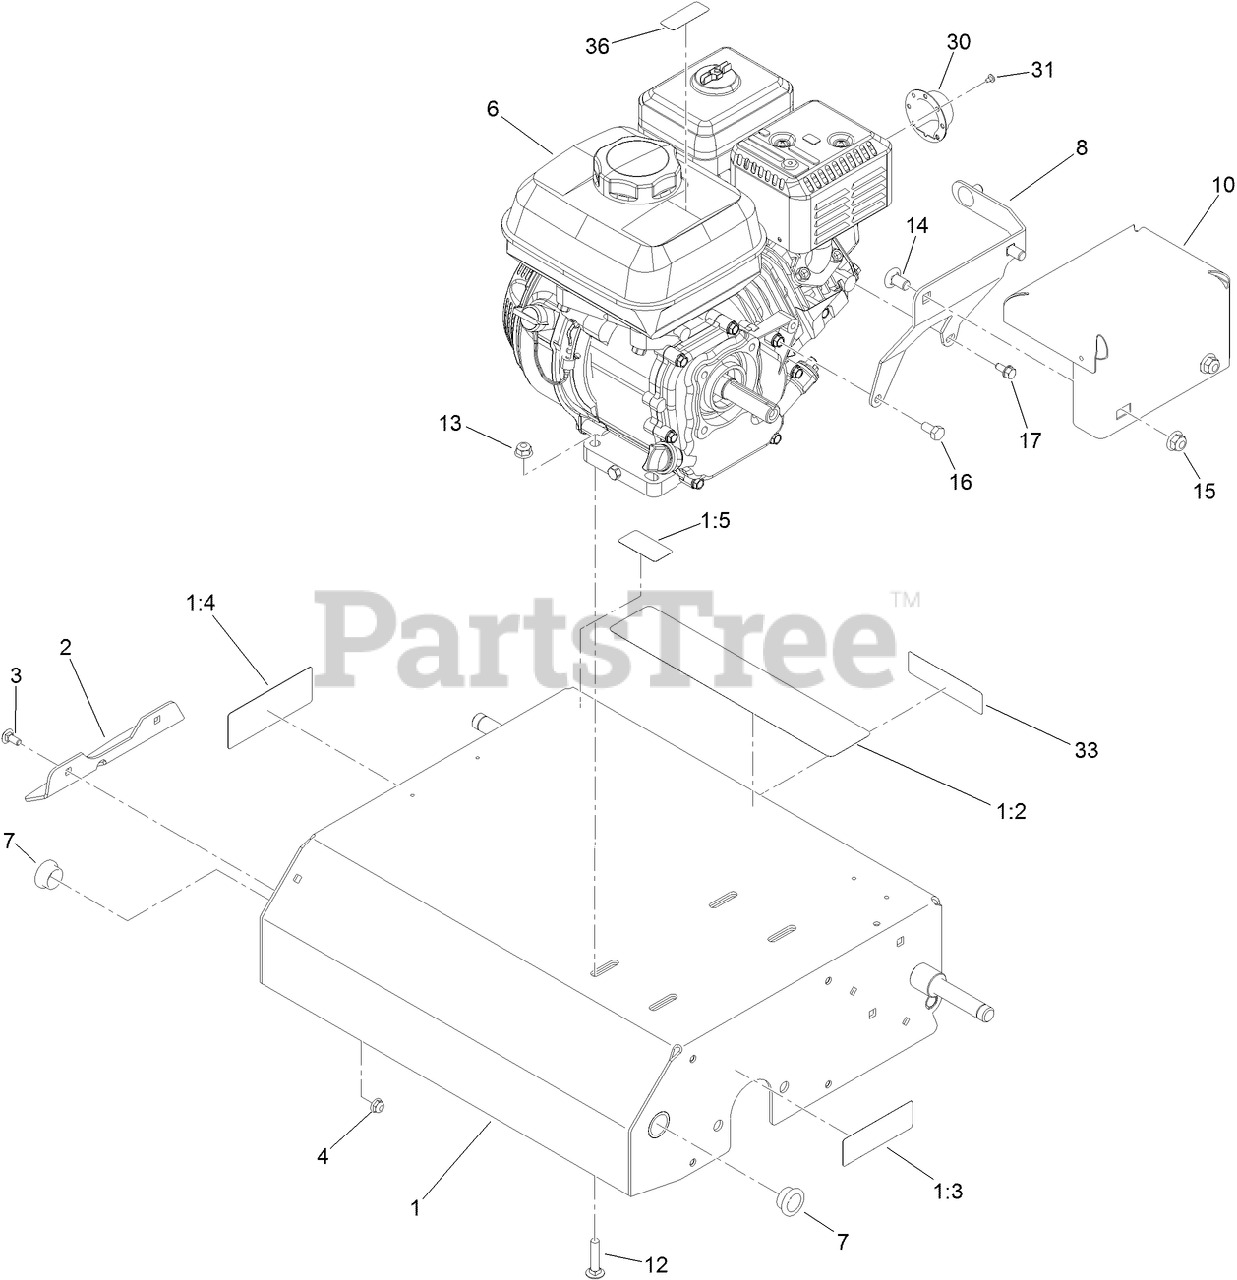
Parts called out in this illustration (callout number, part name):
1	FRAME ASM
1:2	DECAL-WARNING
1:3	DECAL-WARNING
1:4	DECAL-DANGER
1:5	DECAL-PROTECTION, EAR
2	GUARD-HAND
3	SCREW-CARR
4	NUT-HF
7	BUSHING
8	MOUNT-SHIELD, HEAT
10	SHIELD-HEAT
12	BOLT-CARR
13	NUT-HF, NI
14	SCREW-CARR
15	NUT-HF, NI
16	SCREW-HH
17	SCREW-HWH
30	DEFLECTOR
31	SCREW-PPHTF
33	DECAL-ARRESTER, SPARK
36	DECAL-WARNING, ETHANOL
